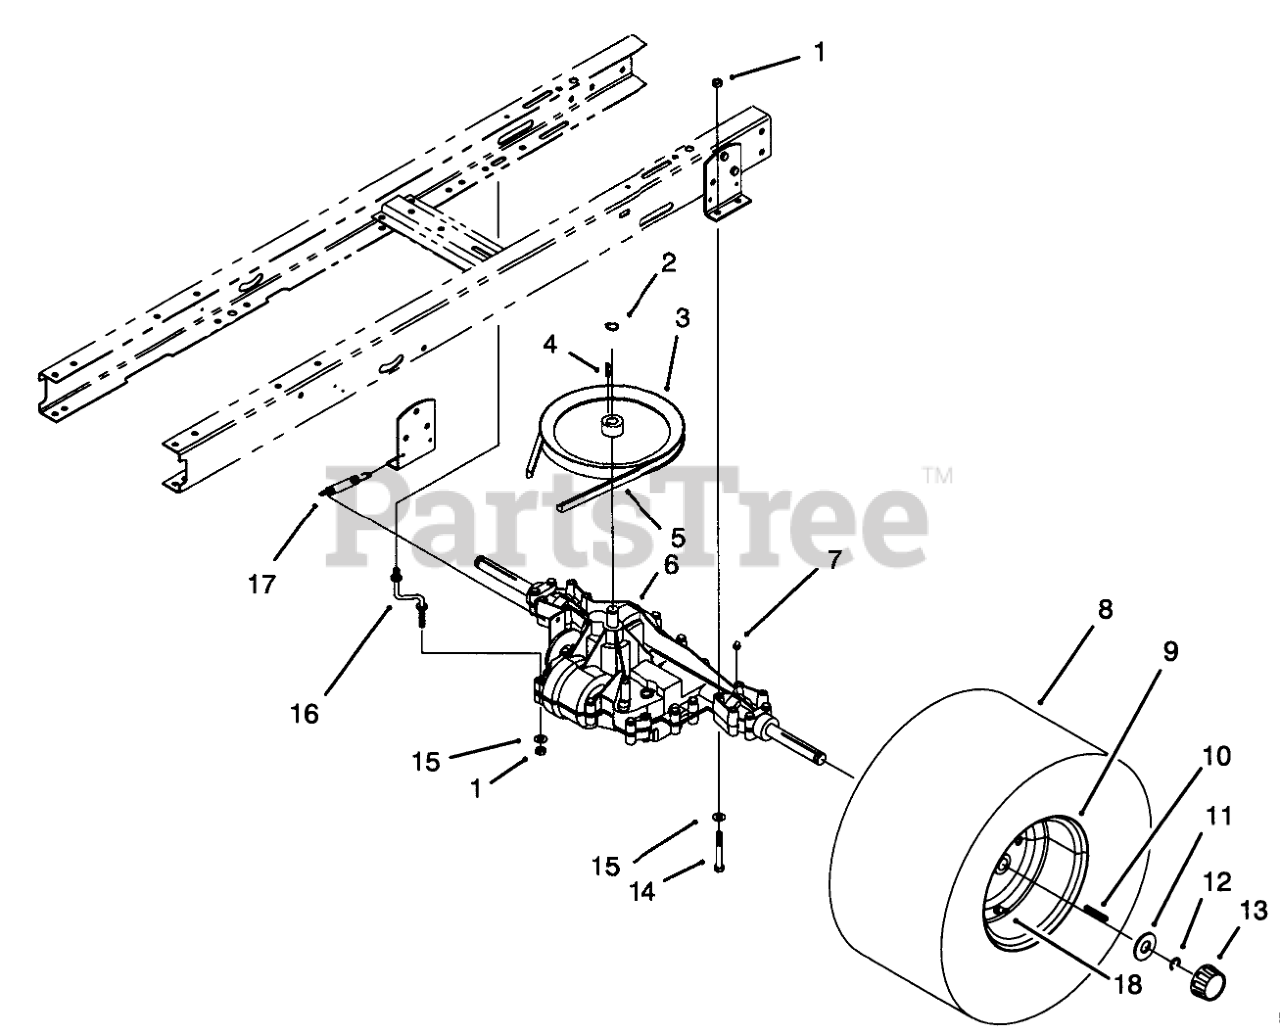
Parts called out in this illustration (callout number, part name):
1	NUT-LOCK, NI
2	RING-SNAP, EXTERNAL
3	PULLEY-TRANSMISSION
4	KEY-WOODRUFF
5	V-BELT
6	Transaxle
7	FITTING-LUBE, 45 DEG
8	TIRE 16 X 6.50 X 8
9	RIM ASM
10	KEY-SQUARE
11	WASHER-PLAIN
12	E-RING
13	CAP-HUB
14	SCREW-HH
15	WASHER-PLAIN
16	TORQUE STRAP
17	SPRING-RETURN, BRAKE
18	STEM-VALVE
